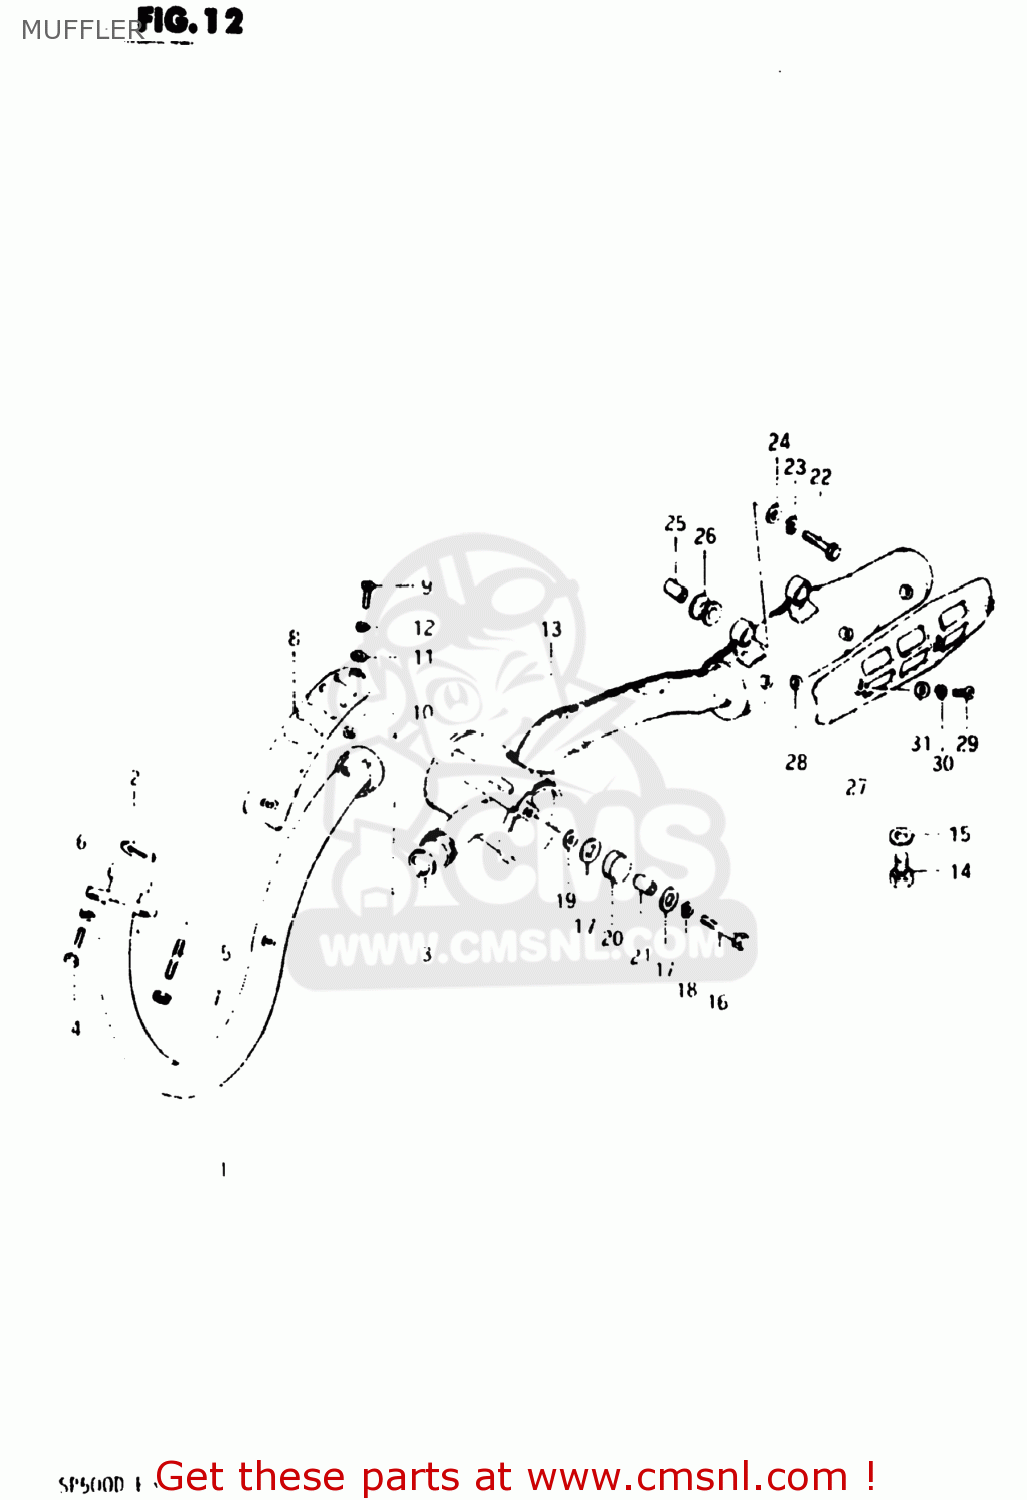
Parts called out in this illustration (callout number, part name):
1	PIPE,EXHAUST
2	GASKET,EXHAUST PIPE (NAS)
3	GASKET,EXHAUST PIPE (NAS)
4	BOLT
5	STUD BOLT
6	LOCK WASHER
7	NUT
8	COVER,EXHAUST PIPE
9	SCREW
10	GASKET 6.2X12X1.5 (MCA)
11	WASHER
12	LOCK WASHER
13	MUFFLER ASSEMBLY
14	PLUG(12X9)
15	GASKET(12X16X2) (NAS)
16	BOLT
17	WASHER (8.5X20X1.6)
18	LOCK WASHER
19	GASKET
20	CUSHION
21	SPACER (8.6X13.8X13)
22	BOLT 8X40
23	LOCK WASHER
24	WASHER (8.5X20X1.6)
25	SPACER (8.6X12X17.5)
26	CUSHION
27	COVER,SECOND MUFFLER
28	GASKET 6.2X12X1.5 (MCA)
29	SCREW
30	LOCK WASHER
31	WASHER
